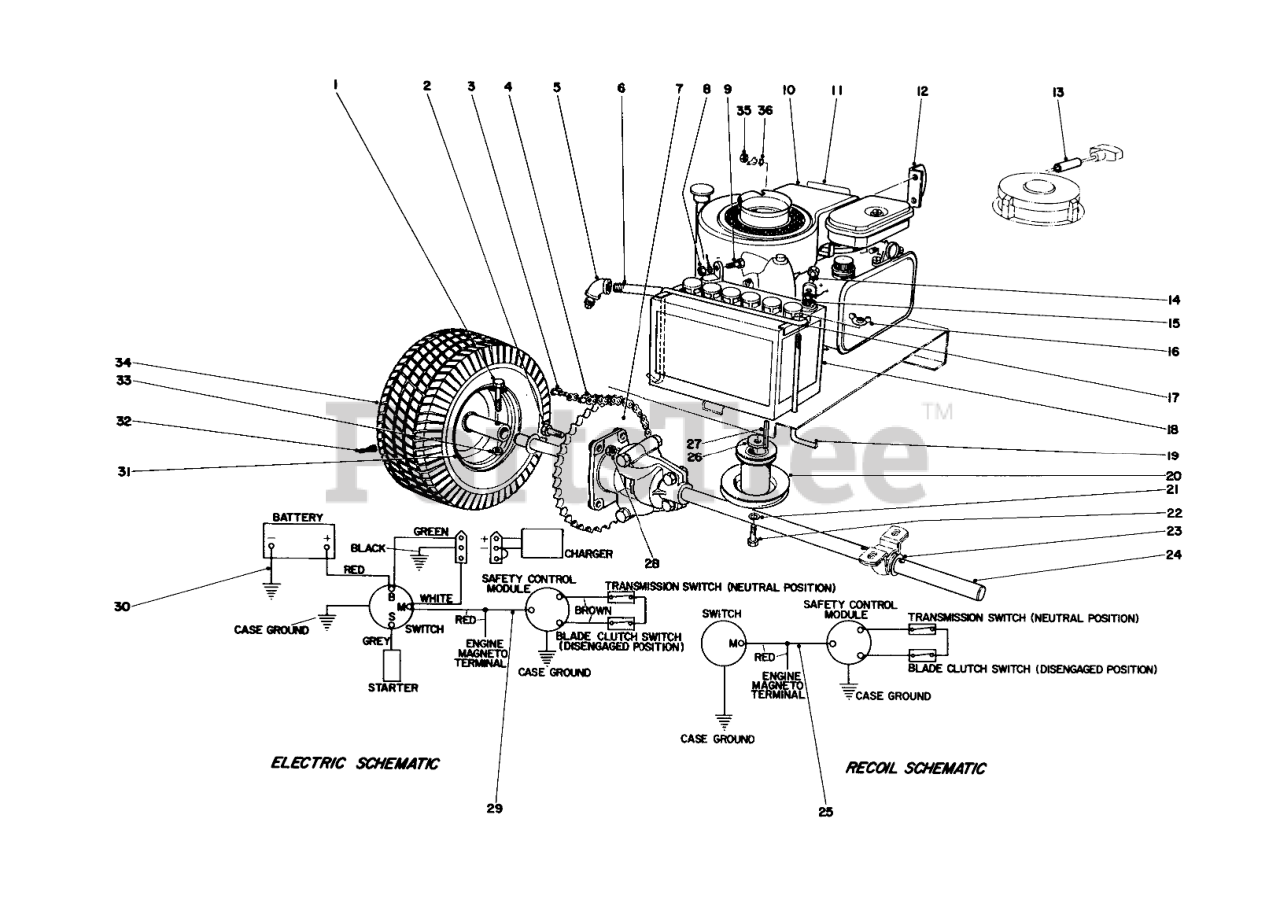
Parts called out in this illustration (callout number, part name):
1	SCREW-HH
2	SCREW-HH
3	LINK-CONNECTING
4	Chain
5	ELBOW - 45 DEGREES
6	NIPPLE
7	Sprocket
8	NUT-HEX
9	SCREW-HH
10	Engine for (Model 56575)
11	Caution Decal
12	Plate Plug Protector
13	Spacer-Starter Rope (Model 56525)
14	SCREW-HH
15	NUT-HEX
16	NUT-WING SPECL
17	Battery Clamp
18	Battery
19	ROD-SUPPORT, BATTERY
20	Pulley
21	WASHER-LOCK
22	SCREW-HH
23	WASHER
24	Differential
25	Wire Harness (Model 56525)
26	Spacer
28	NUT-LOCK, CONE
29	Wire Harness (Model 56575)
30	Wire Assembly (Model 56575)
32	STEM-VALVE
33	NUT-LOCK, CONE
34	Terra Tire
35	NUT-HEX
36	WASHER-LOCK
